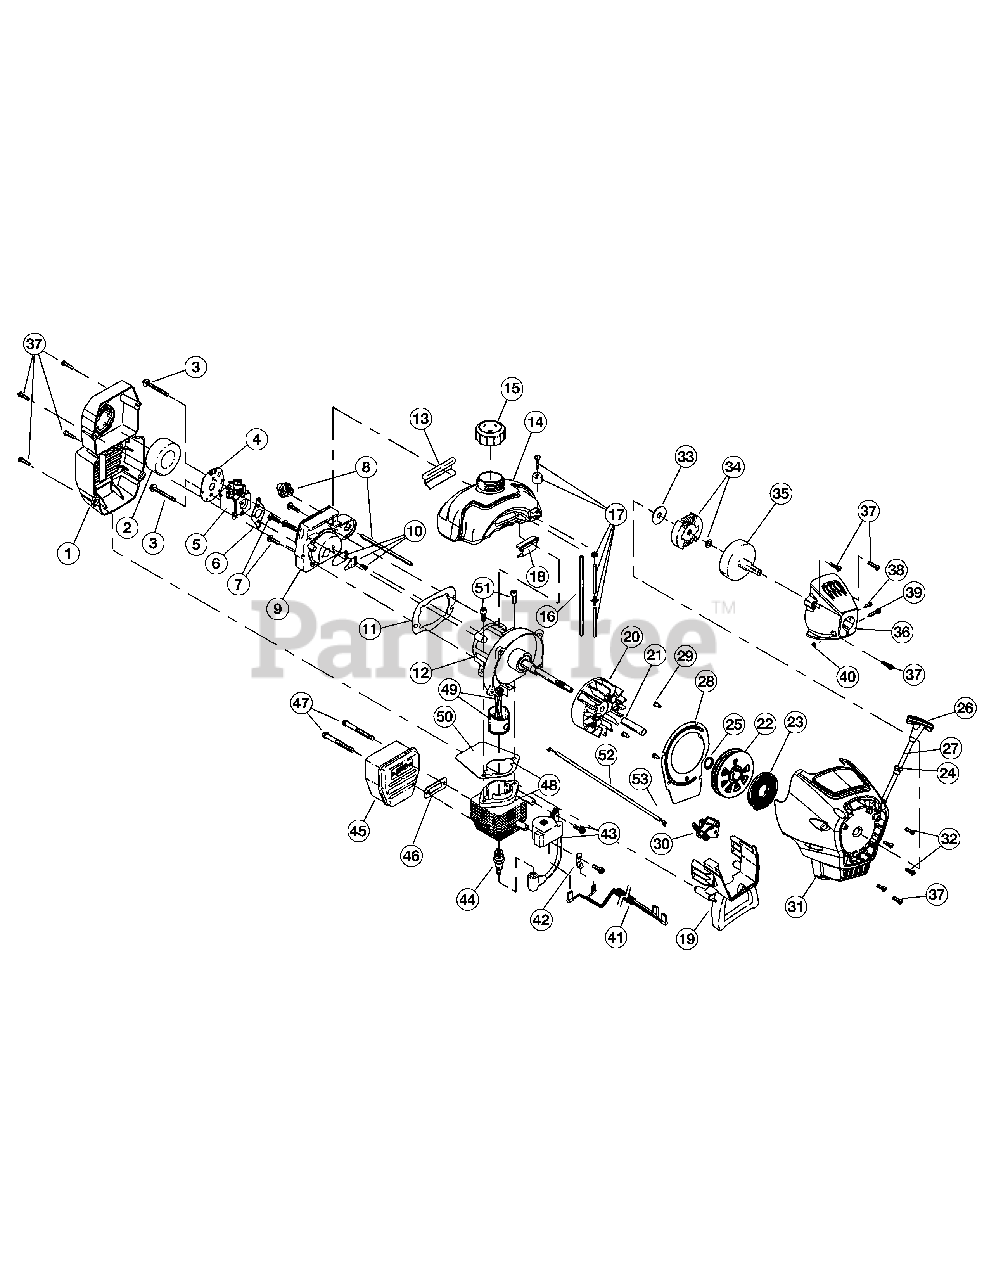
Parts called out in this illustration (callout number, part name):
1	Air Cleaner Assembly (includes 2 & 37)
2	Air Cleaner Filter
3	Carburetor Mounting Screw Assembly
4	Choke Plate
5	Carburetor Assembly (includes 6 & 17)
6	Carburetor Gasket
7	Carb Mount Screw
8	Primer and Hose Assembly
9	Carb Mount Assembly (includes 7, 10 & 11)
10	Reed Assembly
11	Carburetor Mount Gasket
12	Crank Case Service Assembly (includes 7)
13	Rear Mounting Pad
14	Fuel Tank Assembly (includes 15-17)
15	Fuel Cap Assembly
16	Fuel Return Line
17	Fuel Line Assembly
18	Front Mounting Pad
19	Shroud Extension & Stand (includes 37)
20	Flywheel Assembly
22	Recoil Pulley Assembly (includes 25)
23	Recoil Spring
24	Rope Guide
25	Palnut
26	Pull Handle
28	Pressure Plate Assembly (includes 29)
29	Plate Screw
30	ACL Lever Assembly (includes 53)
31	Starter Housing Assembly (includes 22-30, 32, 37 & 52)
32	Housing Screw
33	Clutch Washer
34	Clutch Rotor Assembly
35	Clutch Drum Assembly
36	Clutch Cover Assembly (includes 37-40)
37	Cover Screw
38	Anti-Rotation Screw
39	Clamping Screw
40	Clamping Nut
41	Wire Leads and Sleeve
42	Ground Tab
43	Module Assembly (includes 42)
44	Spark Plug
45	Muffler Assembly (includes 46, 47 & Spark Arrestor)
46	Exhaust Gasket
47	Muffler Mounting Bolt Assembly
48	Cylinder Assembly (includes 50 & 51)
49	Piston and Rod Assembly
50	Cylinder Gasket
51	Cylinder Bolt
52	ACL Throttle Cable
53	Screw
